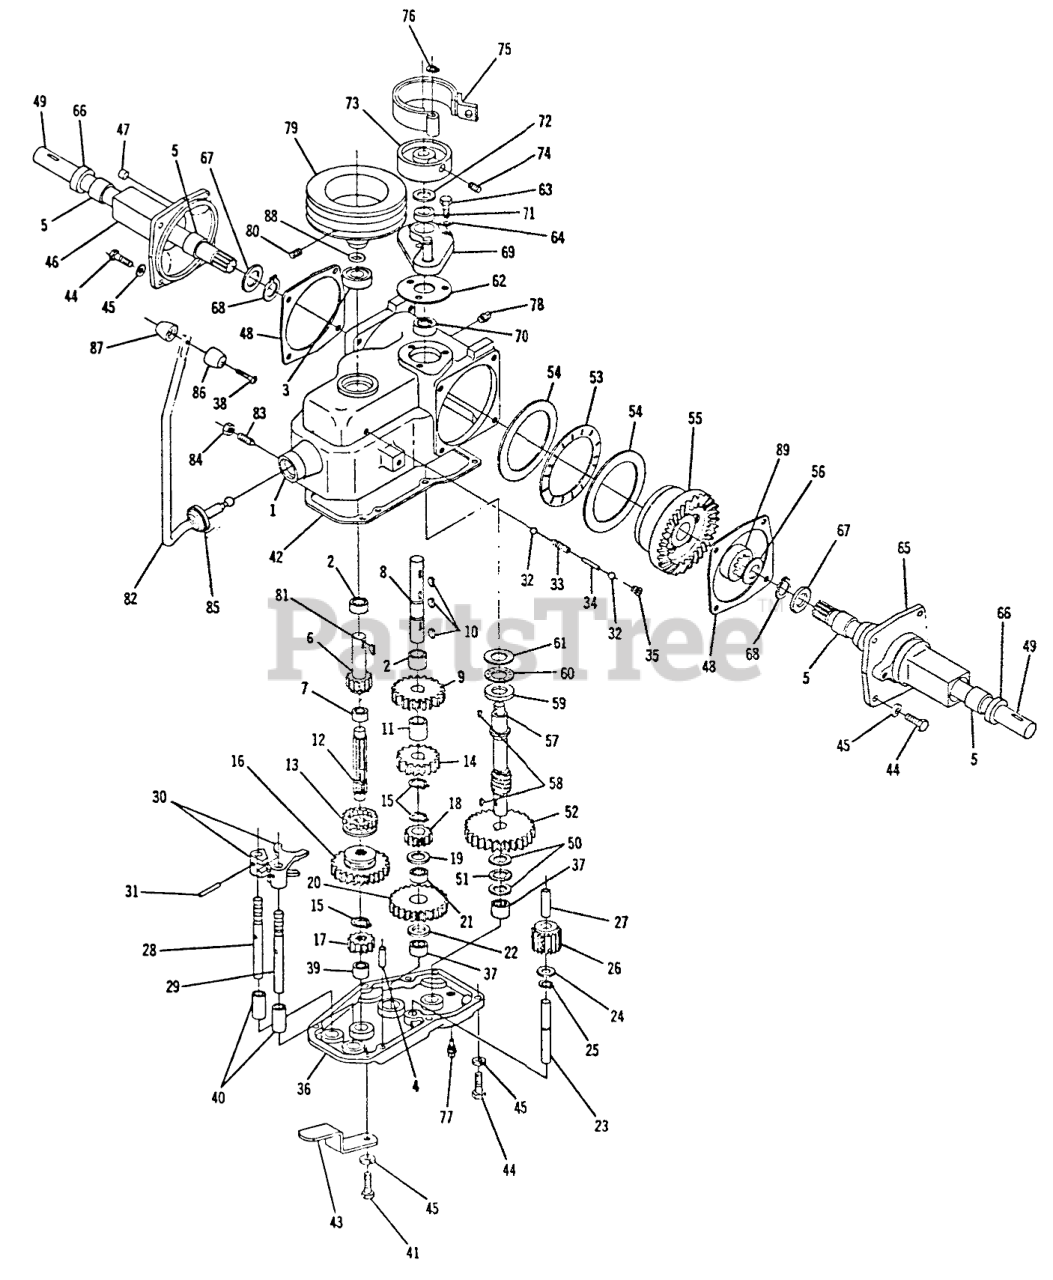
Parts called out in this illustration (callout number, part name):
1	Housing-Gear Case
2	BEARING-NEEDLE
4	PIN-DOWEL
5	BEARING-NEEDLE
7	BEARING-NEEDLE
8	Shaft Idler
17	GEAR
18	Gear-1st Speed
19	WASHER-THRUST
21	BEARING-NEEDLE
23	Shaft-Reverse Idler
24	RACE THRUST
26	GEAR/BUSHING ASM-REVERSE IDLER
27	BUSHING
28	RAIL-SHIFT
29	RAIL-REAR SHIFT
31	PIN-ROLL
32	BALL-DETENT
34	PIN-SHIFT
37	BEARING-NEEDLE
38	Bolt #10-24 x 1 1/4
40	Bushing-Shifter Rail
41	Bolt 3/8-16 x 1
44	Bolt 3/8-16 x 1
45	Lockwasher
55	Differential Assembly
58	KEY WOODRUFF
61	Rae-Thrust
63	Bolt 5/16-18 x
64	Lockwasher
65	Housing Axle L.H.
72	WASHER-THRUST
74	Screw 1/4-20 x 5/8
77	Plug 1/4 Pipe
80	Set Screw-Nylok
81	Key
83	SETSCREW
84	Nut 1/4-20
86	KNOB
87	KNOB
88	O-Ring
89	Bearing Axle
